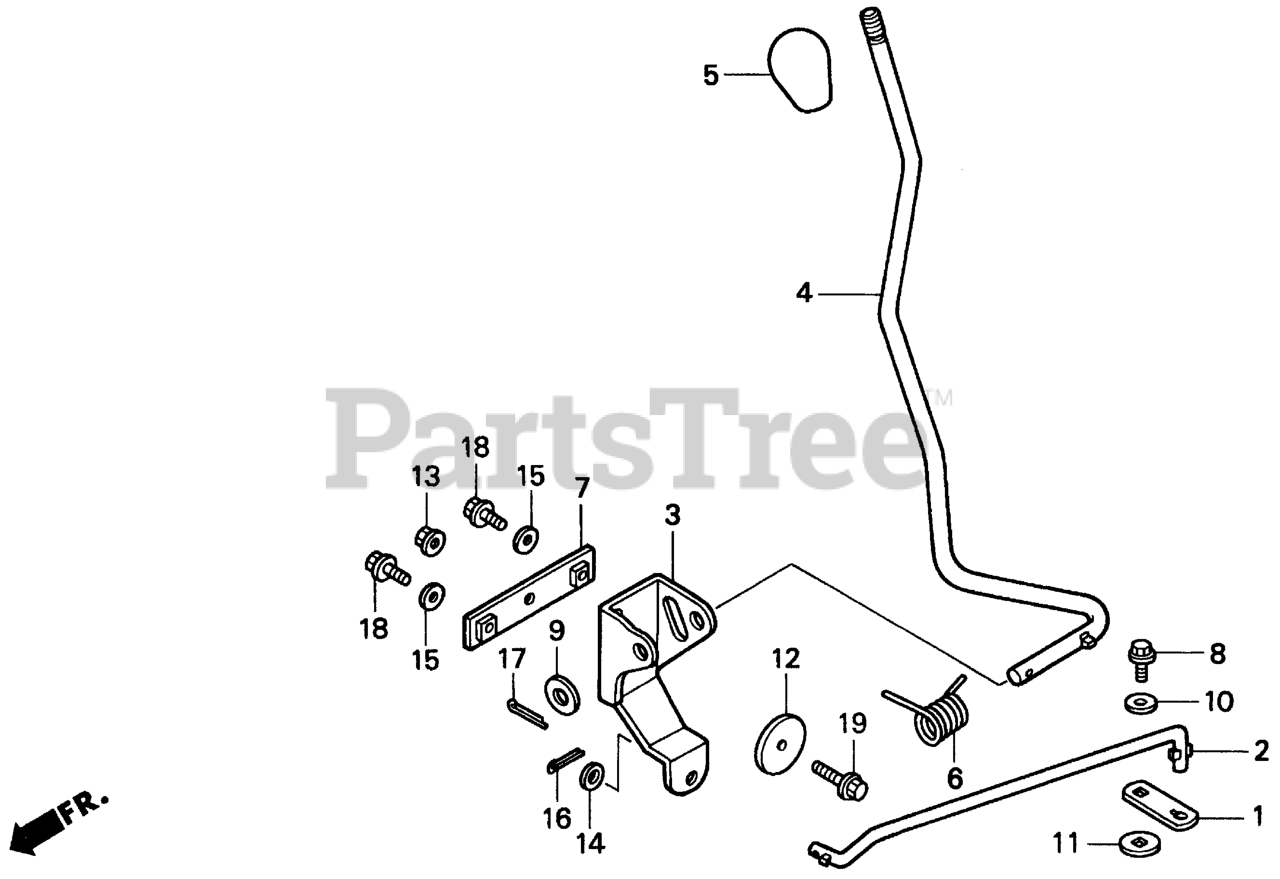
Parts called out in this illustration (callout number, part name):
1	ARM, CHANGE
2	ROD, GEARSHIFT
3	ARM, CHANGE LEVER
4	LEVER, CHANGE
5	GRIP, CHANGE LEVER
6	SPRING, CHANGE LEVER
7	HOLDER, CHANGE ARM
8	BOLT, FLANGE (1/4")
9	WASHER, SPECIAL
10	WASHER (6MM)
11	WASHER, CHANGE ARM
12	COLLAR, TENSIONER ARM
13	NUT, FLANGE (8MM)
14	WASHER, PLAIN (10MM)
15	WASHER, PLAIN (8MM)
16	PIN, SPLIT (4.0X20)
17	PIN, COTTER (4X25)
18	BOLT, FLANGE (8X18)
19	BOLT, FLANGE (8X28)
